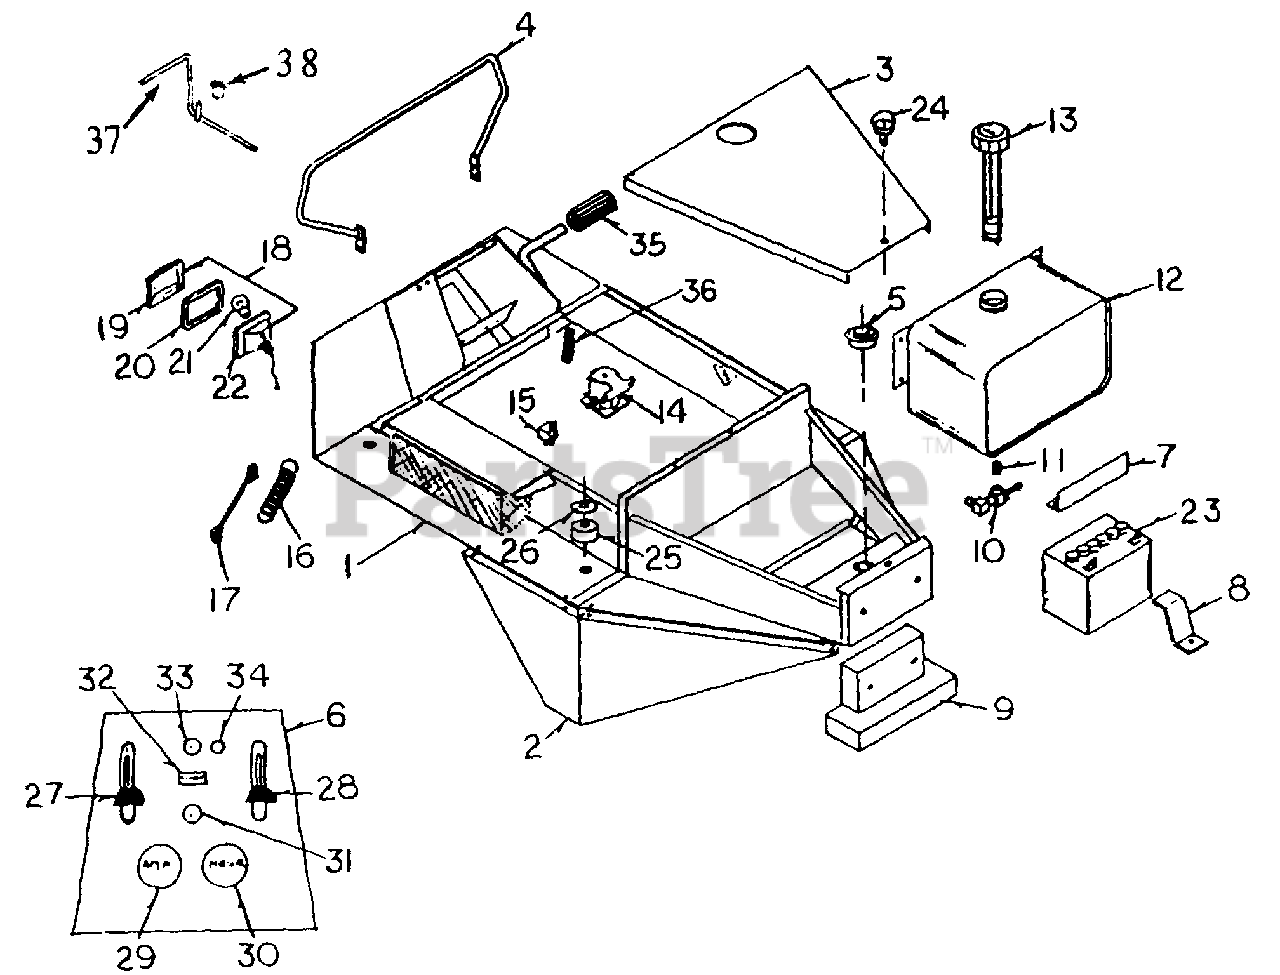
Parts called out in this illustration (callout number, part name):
1	Body
2	Fender, LH
7	Hold Down, Battery
8	Battery Post Protector
9	Tail Weight
10	Shutoff Valve, Fuel
11	Nipple, 1/8" x Close
13	Fuel Tank Cap w/Gauge
15	Relay
17	Deck Lift Cable
18	Light Assembly
19	Lens
20	Gasket
21	Bulb
23	Battery
25	Rubber Body Mount
26	Body Mount Washer
28	Throttle Cable
31	Ignition Switch
32	Light Switch
33	Clutch Switch
35	Brake Pedal Pad
37	Lever - Brake Lock
38	Pivot - Lever
